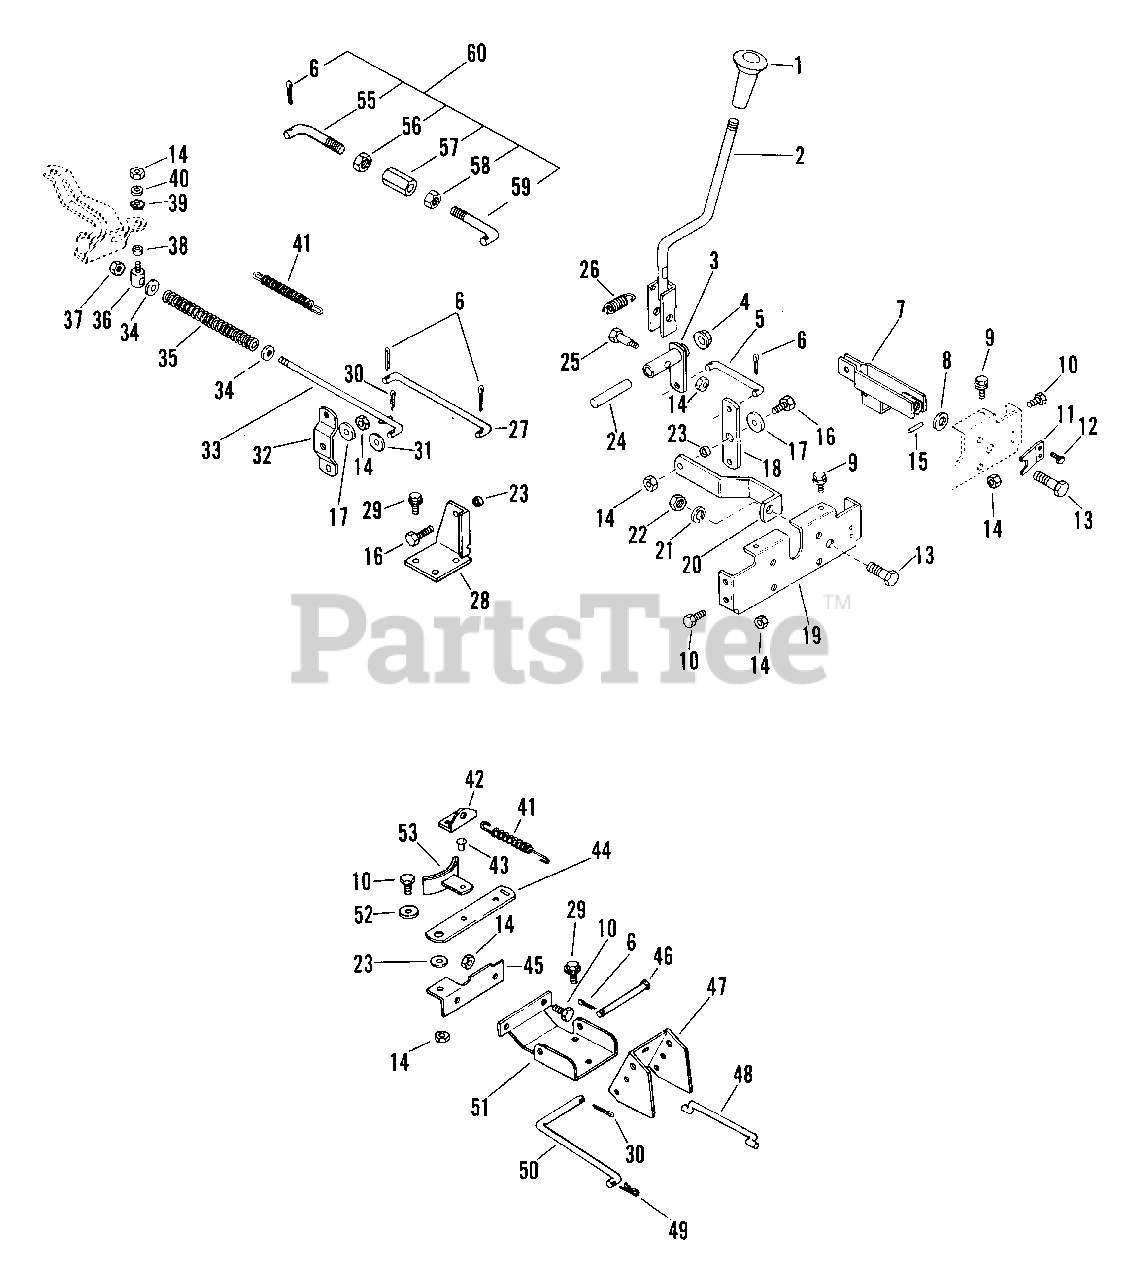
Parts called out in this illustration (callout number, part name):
2	MOWER CLUTCH LEVER
3	CLUTCH ARM
4	FLANGE BUSHING
5	LINK
6	PIN-COTR .09X.75 PL
7	ADJUSTMENT YOKE
8	WSHR-FL-STL .505X1.000X.062
9	SCR-TAP .250-20X.50 HXSLHDPL
10	BLT-HEX .31-18X.63 PL GR 2
11	LOCK SPRING
12	SCR-TAP 10-24X.25 CRSLPH PL 1A
13	CAP SCREW
13	BLT-HEX .50-13X1.25 PL GR2
14	NUT-LK .312-18 GR A PL
15	PIN-ROLL .188X1.00
16	BLT-HEX .31-18X.88 PL GR2
17	WSHR-FL-STL .344X1.125X.063PL
18	CLUTCH LINK
19	MOWER ADJUSTMENT BRACKET
20	FRONT ANCHOR
21	WSHR-LK .500X.151 HVY PL
22	NUT .50-13 PL
23	SPACER BUSHING .5 X .32 X .163
25	SHOULDER BOLT .436 X .912
26	SG-TENS .092X.69X1.75 WLD 54
27	CLUTCH ROD
28	DECK PIVOT BRACKET
29	SCR-TAP .312-18X.50 HWH PL TR
30	PIN-COTR .12X.75 PL
31	WSHR-FL-STL.344X.688X.065PL
32	ARM
33	CLUTCH ROD
34	WSHR-FL-STL .38X.875X.083 PL
35	SG-COMP .148X.68X6.5 WLD 90
36	ROD PIVOT
37	NUT-LK-CTR .375-16 GR A PL
38	SPACER BUSHING .5 X .32 X .21
39	WAVE WASHER .531X.781X.125FH
40	WSHR-FL-STL .323X.625X.062 PL
41	SG-TENS .072X.51X5.31 WLD 25
42	BRAKE CLIP
43	RVT .25X.50 RH ST
44	MOWER BRAKE LEVER
45	BRAKE BRACKET
46	PIN-CLEV .309X3.50 SP
47	MOWER ENGAGING ARM
48	MOWER BRAKE LINK
48	MOWER BRAKE LINK SERVICE ASSY
49	PIN-HAIR INT .08X.38X1.42 YWZC
50	MOWER ENGAGEMENT LINK
51	PIVOT BRACKET
52	WSHR-FL-STL .328X1.0X.094
53	BLADE BRAKE
54	SCR-TAP .250-20X.37 HWH PL TR
55	CLUTCH ROD RH
56	NUT-HEX .375-16
57	NUT-CUPLG RH & LH THD .37-16PL
58	NUT LH THD .375-16 GR 2 PL
59	CLUTCH ROD LH
60	CLUTCH ROD SERVICE ASSY
